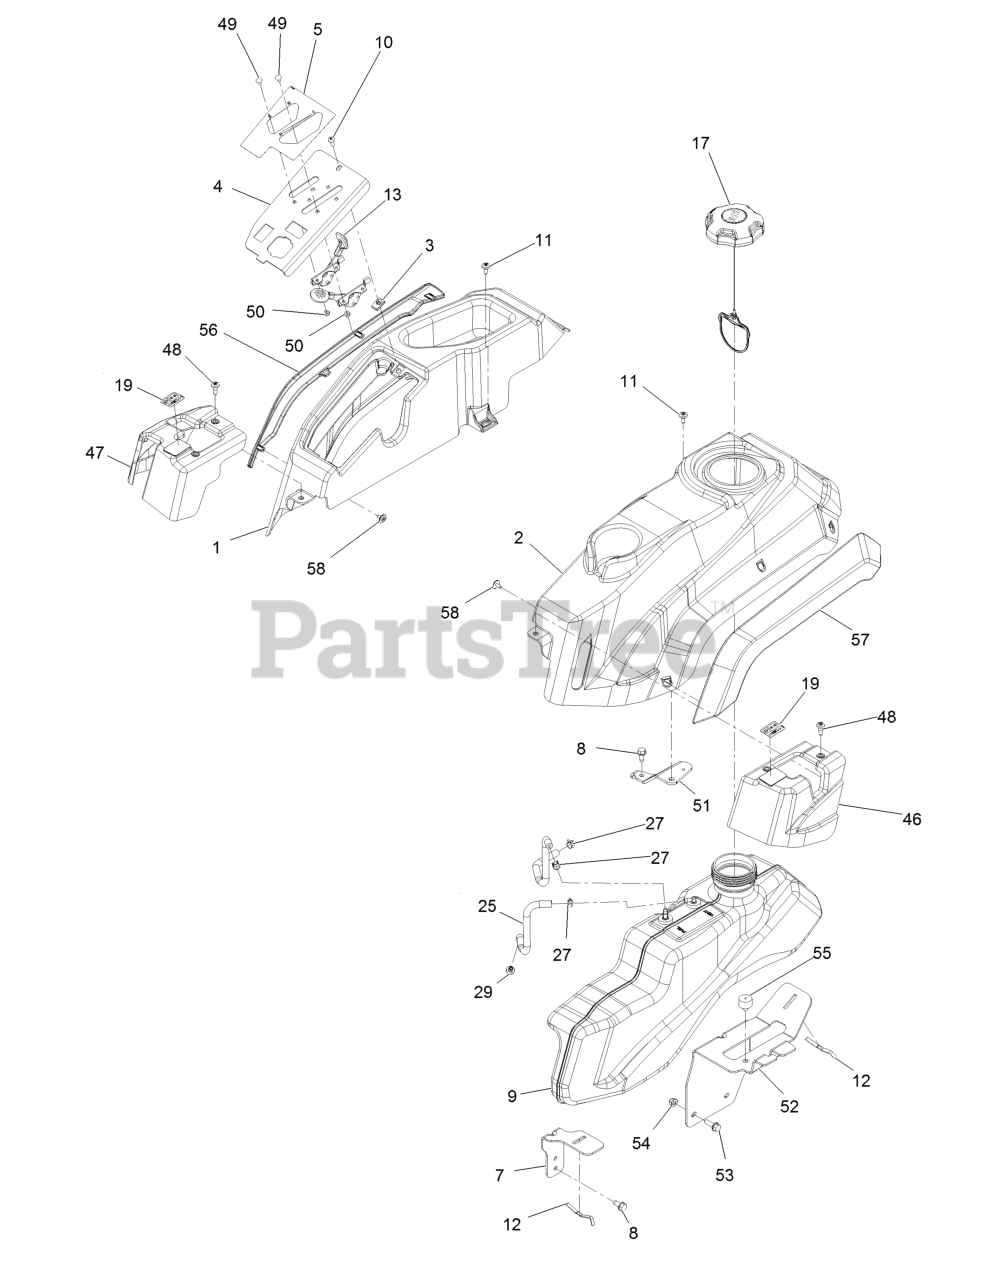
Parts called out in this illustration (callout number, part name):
1	Pod-RH, Narrow
2	Pod-LH, Narrow
3	Nut-Retainer-Panel 1/4-20
4	Plate-Control
4	Panel-Control, Narrow
5	Decal-Control
7	Support-Tank [black]
8	Screw-HWH 5/16-18 X 3/4 Tf
9	Tank, Fuel
10	Screw-PPH 1/4-20 X 3/4
11	Screw-1/4-20 X 1/2 Tf Torx Plus
12	Spring
13	Cable-Control, Throttle
13	Cable-Control, Choke
17	Cap-Fuel, Ratcheting
19	Decal-Motion Control
25	Hose-Fuel Line 10 1/2"
25	Hose-Fuel
27	Clamp-Hose
28	Tie-Cable
29	Adaptor-Orifice
46	Cover, Motion Control LH
47	Cover, Motion Control RH
48	Screw-Shoulder
49	Bolt-Carriage #10-24 X 1/2
50	Nut-Nyloc #10-24
51	Bracket-Clamp
52	Bracket-Support Tank
53	Screw-HH Flg 5/16-18 X 1
54	Nut-Nyloc 5/16-18 Flg
55	Bumper-Grommet
56	Fender-RH
57	Fender-LH
58	Screw-HWH #10-14 X 1/2 Torx
